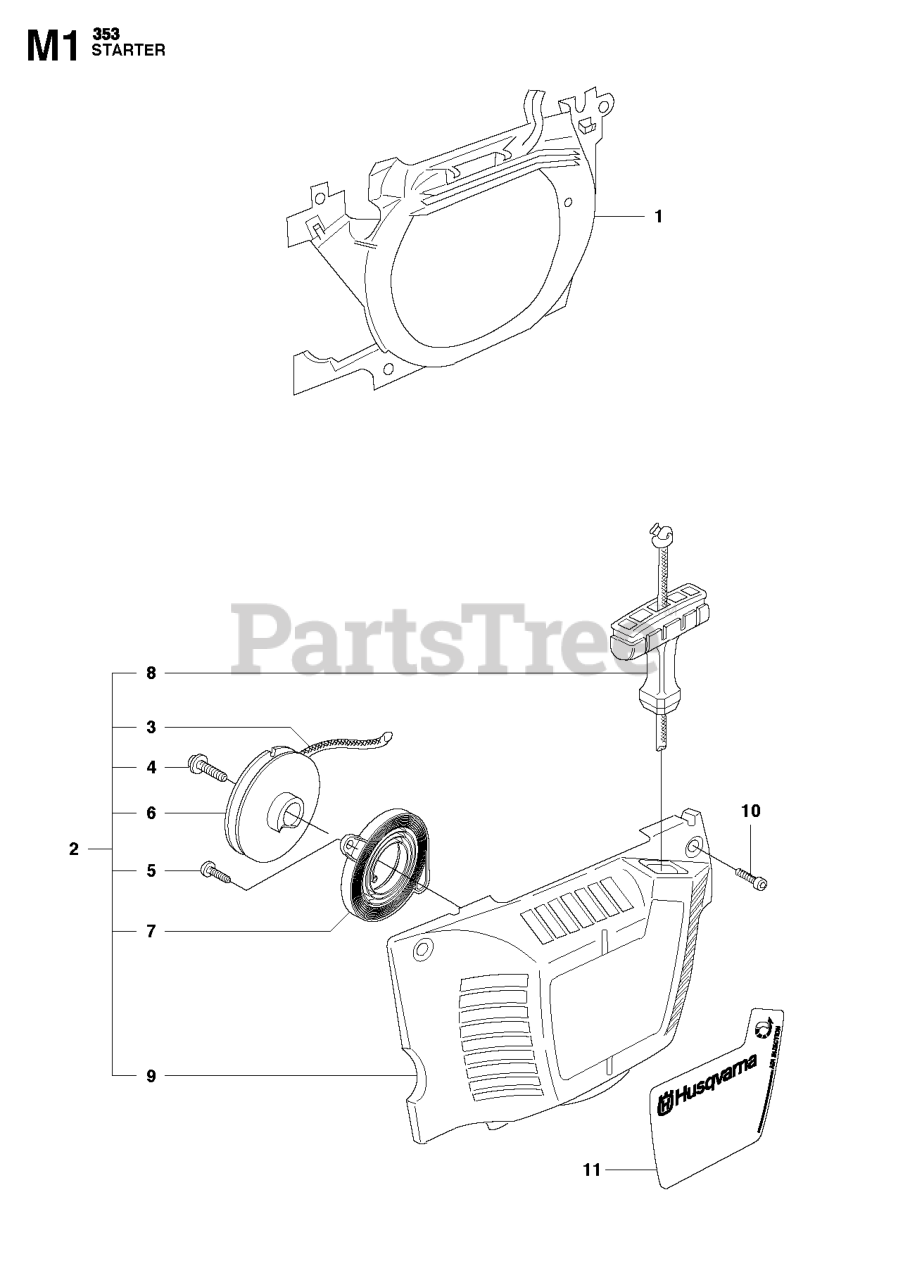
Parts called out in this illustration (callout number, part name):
1	Air Conductors
2	STARTER HOUSING ASSY.
3	STARTER ROPE
6	STARTER PULLEY
7	RETURN SPRING
8	STARTER HANDLE
9	STARTER HOUSING
10	SCREW.CIHPANMO M5X19 10.9
11	DECAL
